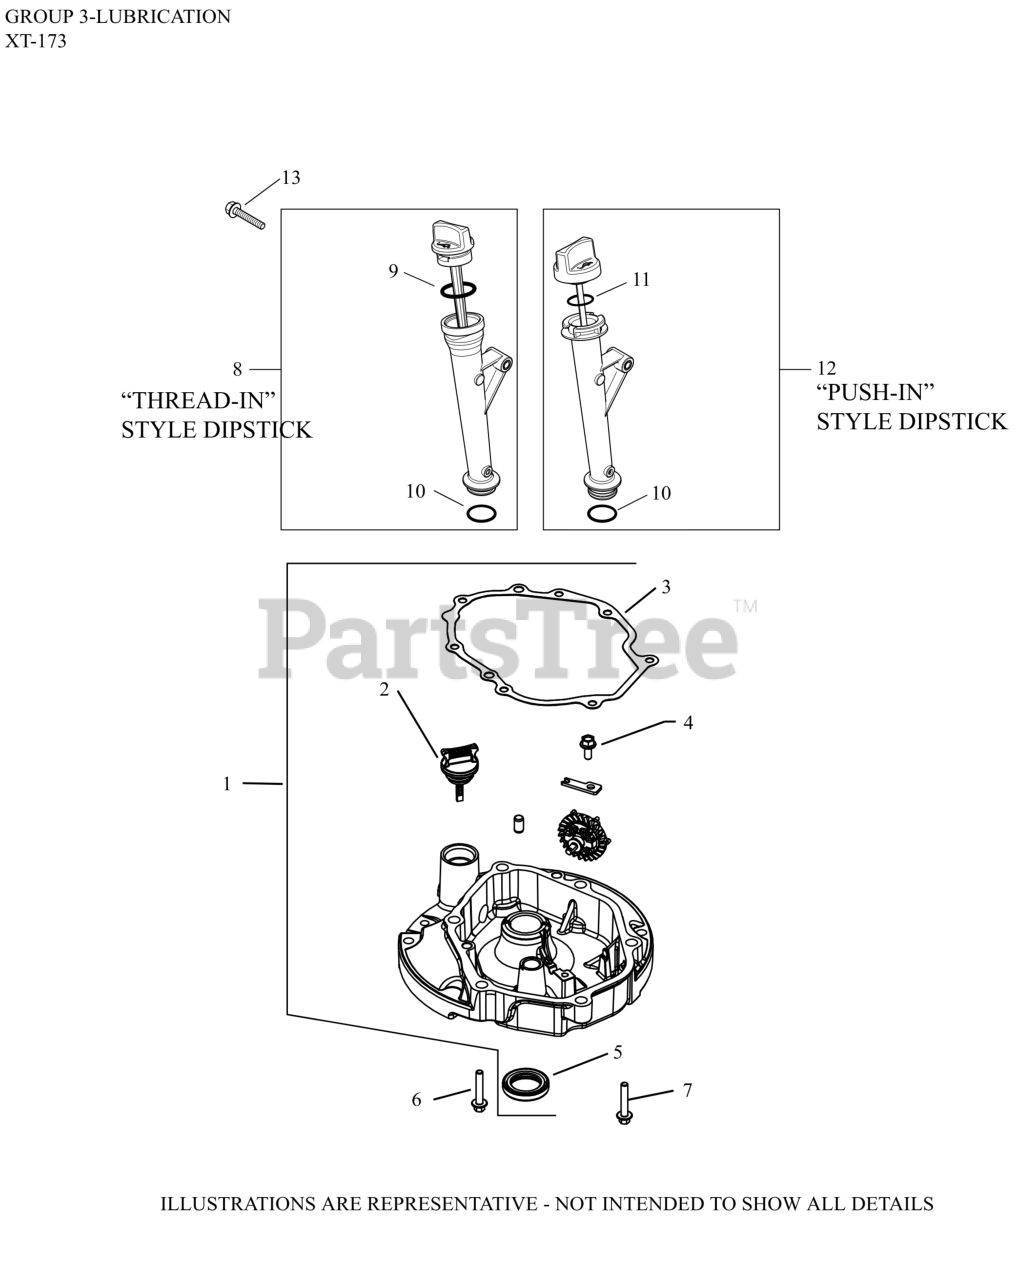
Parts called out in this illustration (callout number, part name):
1	KIT, OIL PAN
3	GASKET, OIL PAN
6	SCREW, HEX FLANGE (M8)-USE 25 086 456-S
7	SCREW, HEX FLANGE (M6)-(#25086435S)
10	O-RING, OIL FILL TUBE
11	O-RING (CAP)
12	KIT, DIPSTICK AND TUBE-(#1412320S)
NI	TUBE ASSEMBLY, OIL FILL
NI	PLUG, PIPE (W/SEALANT)
NI	CAP, DIPSTICK ASSEMBLY
NI	GEAR ASSEMBLY, GOVERNOR
